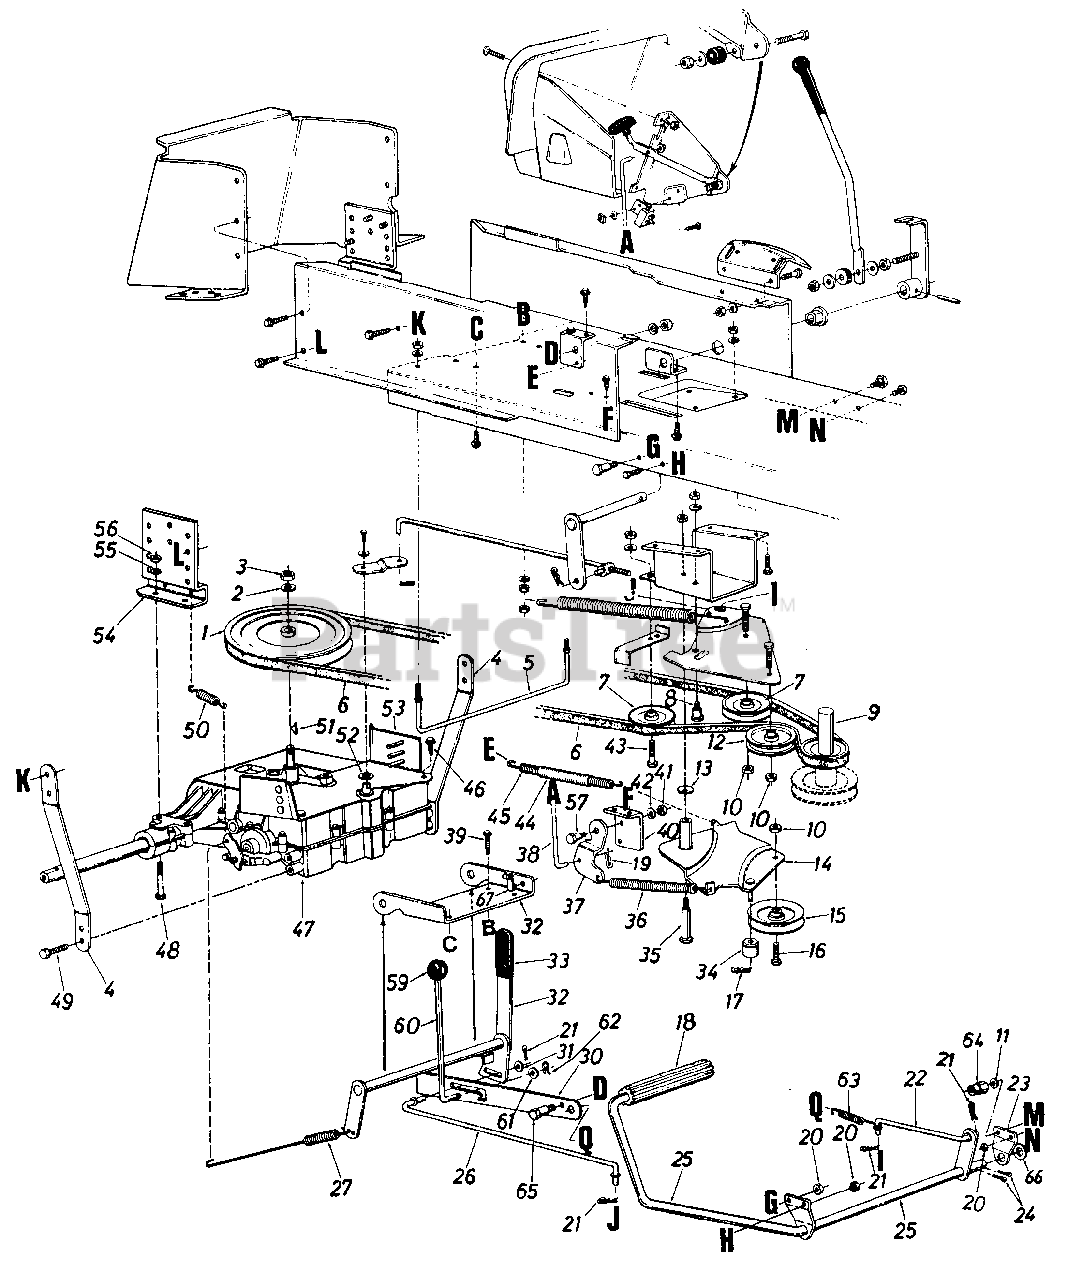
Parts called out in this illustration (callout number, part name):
1	8" "V"-Pulley
2	L-Wash. 1/2" I.D.
3	Hex Nut 1/2-20 Thd.
4	Transaxle Brace
5	Belt Guard
6	"V"-Belt
7	"V"-Belt Idler Pulley .38" I.D. x 3-1/16" O.D.
8	Shoulder Bolt .435" Dia. x .160 (5/16-18)
9	Two Step Engine Pulley 3.10" & 5.56" Dia.
10	Hex Cent. L-Nut 3/8-24 Thd.
11	L-Wash. 3/8" I.D.
12	Flat Idler Pulley 2.75" O.D.
13	Belleville Wash. .400" I.D. x .88" O.D. x .063
14	Idler Bracket Ass'y.
15	4" "V"-Idler Pulley
16	Hex Bolt 3/8-24 x 1.5" Lg.
17	Hairpin Cotter 5/16" Dia.
18	Foot Pad
19	Intern. Cotter Pin 5/16" Dia.
20	Hex Cent. L-Nut 3/8-16 Thd.
21	Hairpin Cotter 3/32" Dia. x 3/4" Lg
22	Brake Clutch Rod (4.60" Lg.)
23	Clutch Rod Bearing Brkt.
24	Cotter Pin 1/8" Dia. x 1.00" Lg.
25	Clutch Brake Pedal Ass'y.
26	Brake Cam Rod (13.60" Lg.)
27	Extension Spring .59" O.D. x.93" Lg.
30	Parking Brake Cam
31	Fl-Wash. .406" I.D. x 1.00" O.D. x .030 Thk.
32	Hand Brake Lever Ass'y.
33	Grip Flat Bar 1-1/4" Wide
34	Spacer
35	Shoulder Bolt .496" Dia. x 2.00" Lg. (3/8-16)
36	Extension Spring .75" O.D. x 6.12" Lg.
37	Deck Control 6rkt.
38	Deck Control Rod
39	Hex Wash. Hd. TT-Tap Scr. 1/4-20 x 1.50" Lg.
40	Parking Brake Cam Mtg. Brkt.
41	Hex Nut 5/16-18 Thd.
42	L-Wash. 5/16" I.D.
43	Hex Bolt 3/8-24 x 1.50" Lg. (Grade 5)
44	Convoluted Conduit .50" I.D. x 4.0" Lg.
45	Ext. Spring .50" O.D. x 6.37"
46	Hex Wash. Hd. AB Tap Scr. 5/16-18 x 518" Lg.
47	Transaxle
48	Hex Bolt 5/16-18 x 2.50" Lg.
49	Hex Wash. Hd. AB Tap Scr. 5/16-18 x 518" Lg.
50	Extension Spring .50" O.D. x 2.75" Lg.
51	Hi-Pro Key 3132" x 518" Dia.
52	Special Wash. 1.00" O.D.
53	Transaxle Belt Keeper Ass'y.
54	Transaxle Support Bracket
55	L-Wash. 5/16" I.D.
56	Hex Nut 5/16-18 Thd.
57	Shoulder Bolt .437" Dia. x .162" Lg. (5/16-18)
59	Ball Knob
60	Parking Brake Link
61	Fl-Wash .
62	Hairpin Cotter
63	Ext. Spring 3.12" Lg.
64	Spacer Nut 3/8-16 Thd.
65	Shld. Bolt .435" Dia. x .16"
66	Fl-Wash. .53" I.D. x .93" O.D.
67	Plastic Hose Clamp
